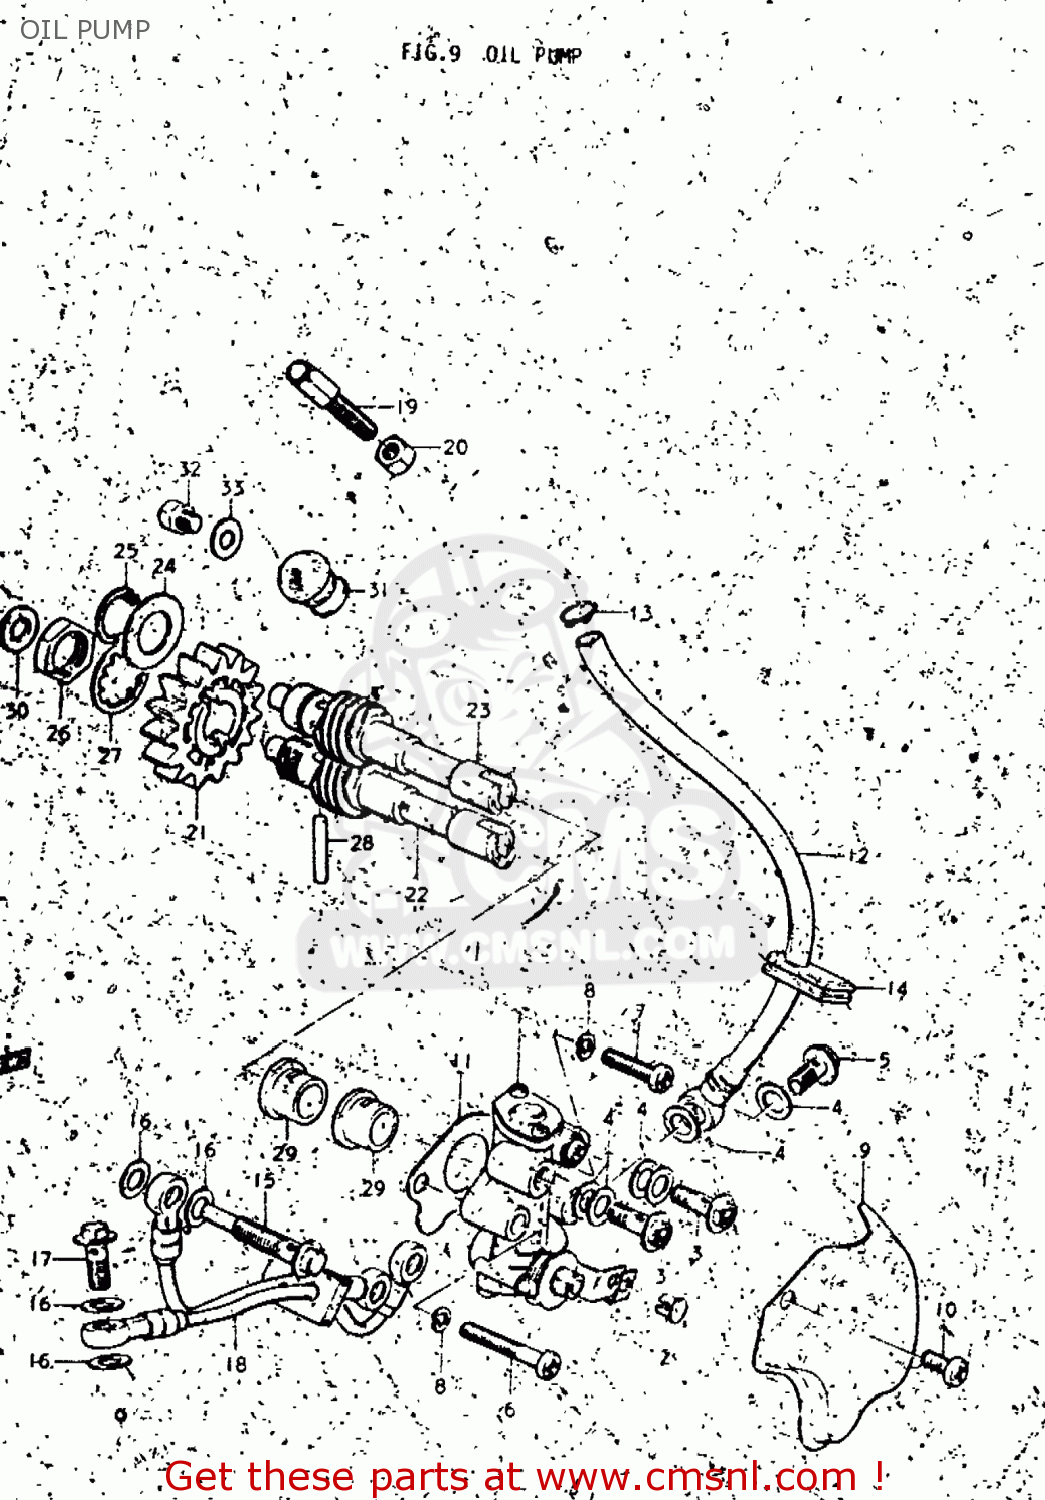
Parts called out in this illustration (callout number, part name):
1	PUMP ASSEMBLY,OIL
2	TERMINAL,CABLE
3	UNION BOLT
4	GASKET (NAS)
5	UNION BOLT
6	SCREW
7	SCREW
8	LOCK WASHER
9	CAP,OIL PUMP INSPECTION
10	SCREW
11	GASKET,OIL PUMP (MCA)
12	HOSE,OIL NO.1
13	CLIP
14	GROMMET
15	UNION
16	GASKET
17	UNION BOLT
18	HOSE,OIL NO.2
19	BOLT
20	NUT
21	GEAR,OIL PUMP DRIVE
22	SHAFT,OIL PUMP IDLE GEAR
23	SHAFT,OIL PUMP IDLE GEAR
24	WASHER, INNER
25	CIRCLIP
26	NUT
27	WASHER,LOCK
28	ROLLER(4X23.8)
29	BUSHING
30	THRUST WASHER
31	Plug
32	BOLT(6X6)
33	WASHER
